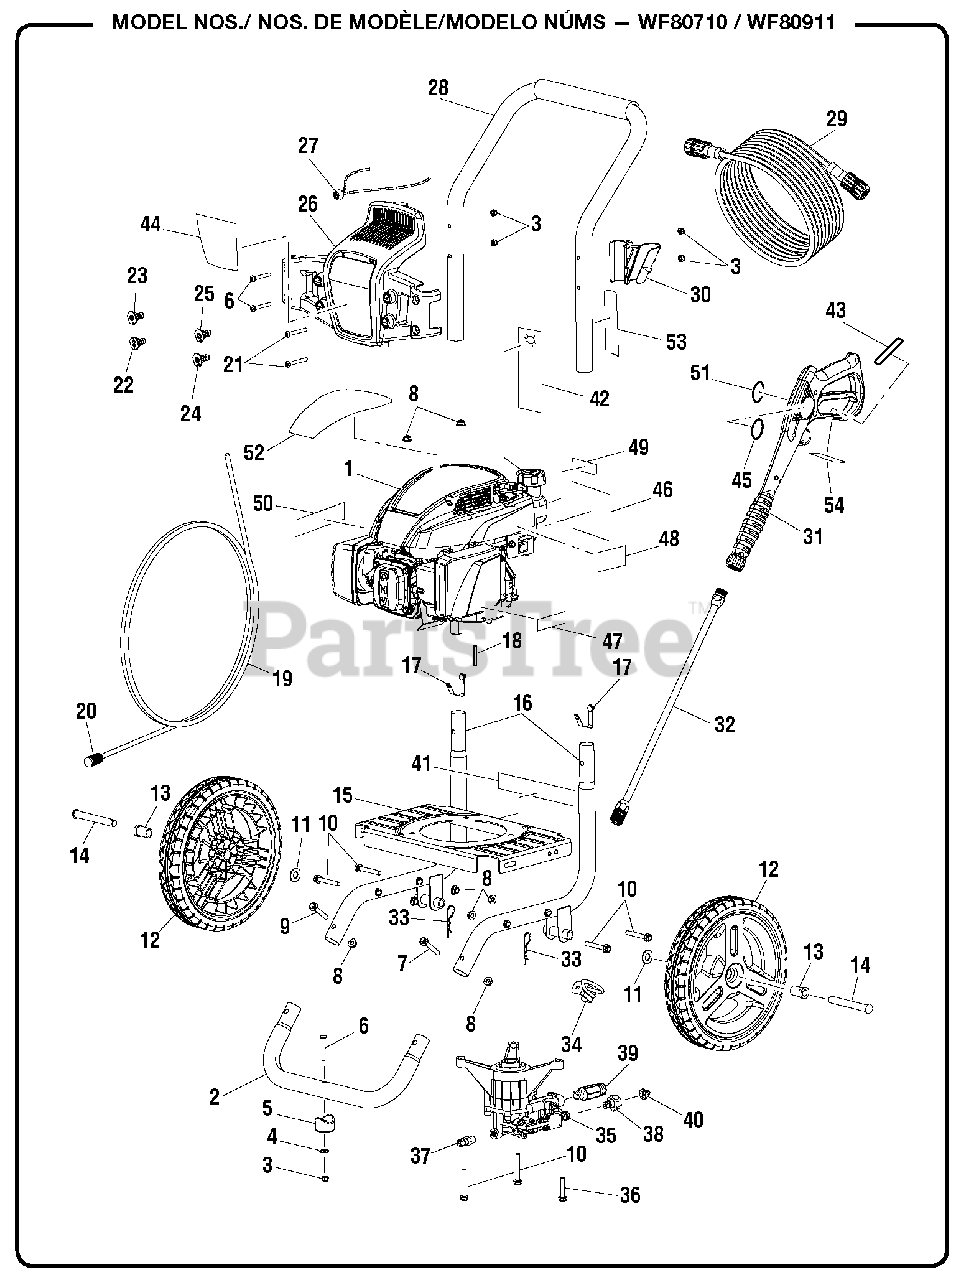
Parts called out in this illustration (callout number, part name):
1	163 cc EPA Engine
1	163cc Carb Engine
2	Front Frame
3	Lock Nut (1/4-20)
4	Washer (1/4 in.)
6	Screw (1/4-20 x 1.85 in., Torx)
7	Bolt (M8 x 50 mm)
8	Lock Nut (M8 x 1-1/4 in.)
9	Bolt (M8 x 45 mm)
10	Bolt (M8 x 55 mm)
11	Washer (1/2 in.)
12	Wheel (12 in. x 2 in.)
13	Axle Sleeve
15	Engine Plate
16	Main Frame Assembly
17	Lock Button w/Spring Clip
18	Output Shaft Key
19	Injection Hose
21	Screw (1/4-20 x 2 in., Torx)
22	40deg Nozzle
23	0deg Nozzle
24	25deg Nozzle
25	Detergent Nozzle
26	Storage Holder (4 Nozzle)
27	Bungee Cord and Bead Assembly
28	Handle Assembly
29	High Pressure Hose (25 ft.)
30	Upper Wand Holder
31	Trigger Handle Assembly
32	Spray Wand
33	Hitch Pin
34	Lower Wand Holder
35	Pump
36	Bolt (M8 x 40 mm Hex Hd.)
37	Thermal Release Valve
38	Inlet Tube
39	Outlet Tube
40	Filter Screen
41	Data Label
42	Hang Tag (Engine Oil Fill)
43	Wand Label (Max Rating)
44	Performance Label
45	Trigger Handle Warning Label
46	Warning Label
47	Engine Quick Start Label
48	Switch Label (Engine Off)
49	Warning Label (Combustion)
50	Hot Surface Label
51	Wand Label
52	Engine Label
53	Pump Quick Start Label
54	Warning Label (French/Spanish)
